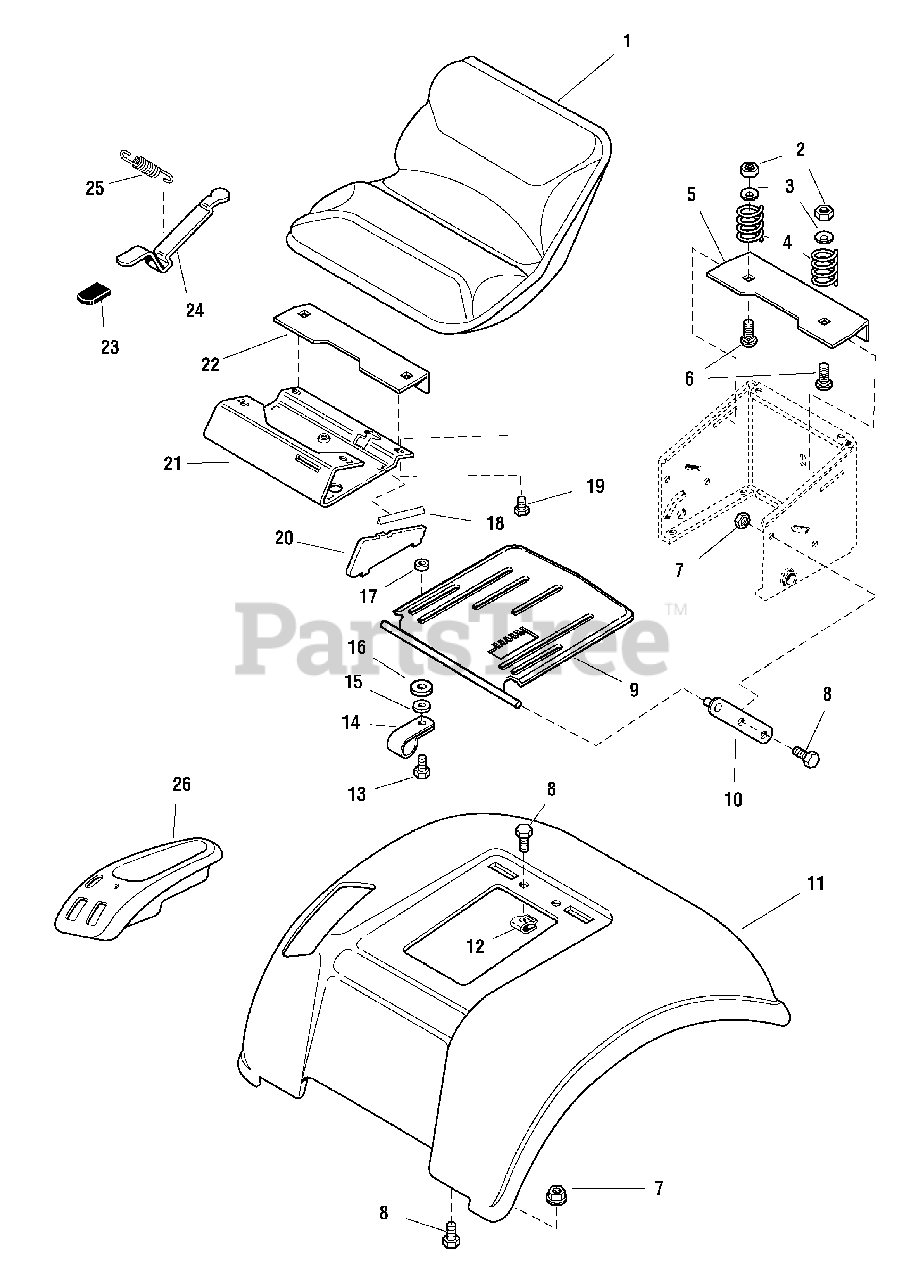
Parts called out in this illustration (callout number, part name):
1	SEAT ASSEMBLY
2	NUT, Hex Nylon Lock, 5/16-18
3	WASHER,5/16
4	SPRING, Seat
5	PLATE, Spring Support
6	CARRIAGE BOLT, 5/16-18 x 3/4
7	NUT, Hex Flange Whiz-Lock, 5/16-18
8	CAPSCREW, Hex Head Whiz Lock, 5/16-18 x 3/4
10	BAR, Seat Pivot
11	SEAT DECK, Orange
11	SEAT DECK, Red
12	SPEED NUT, Tinnerman Lug Type, 5/16-18
13	CAPSCREW, Taptite Hex Washer Head, 5/16-18 x 5/8
14	CLAMP, Wire (Middle Bolt Only)
15	WASHER, 5/16
16	WASHER, Plain
18	EDGING, 3"
19	BOLT, Shoulder, 5/16-18 x 3/4
20	SIDE PANEL, Seat Slide
21	SLIDE, Seat
22	PlATE, Seat Rear
23	CAP, Seat Adjust
24	LEVER, Seat Latch
25	SPRING, Extension
26	CONTROL POD
